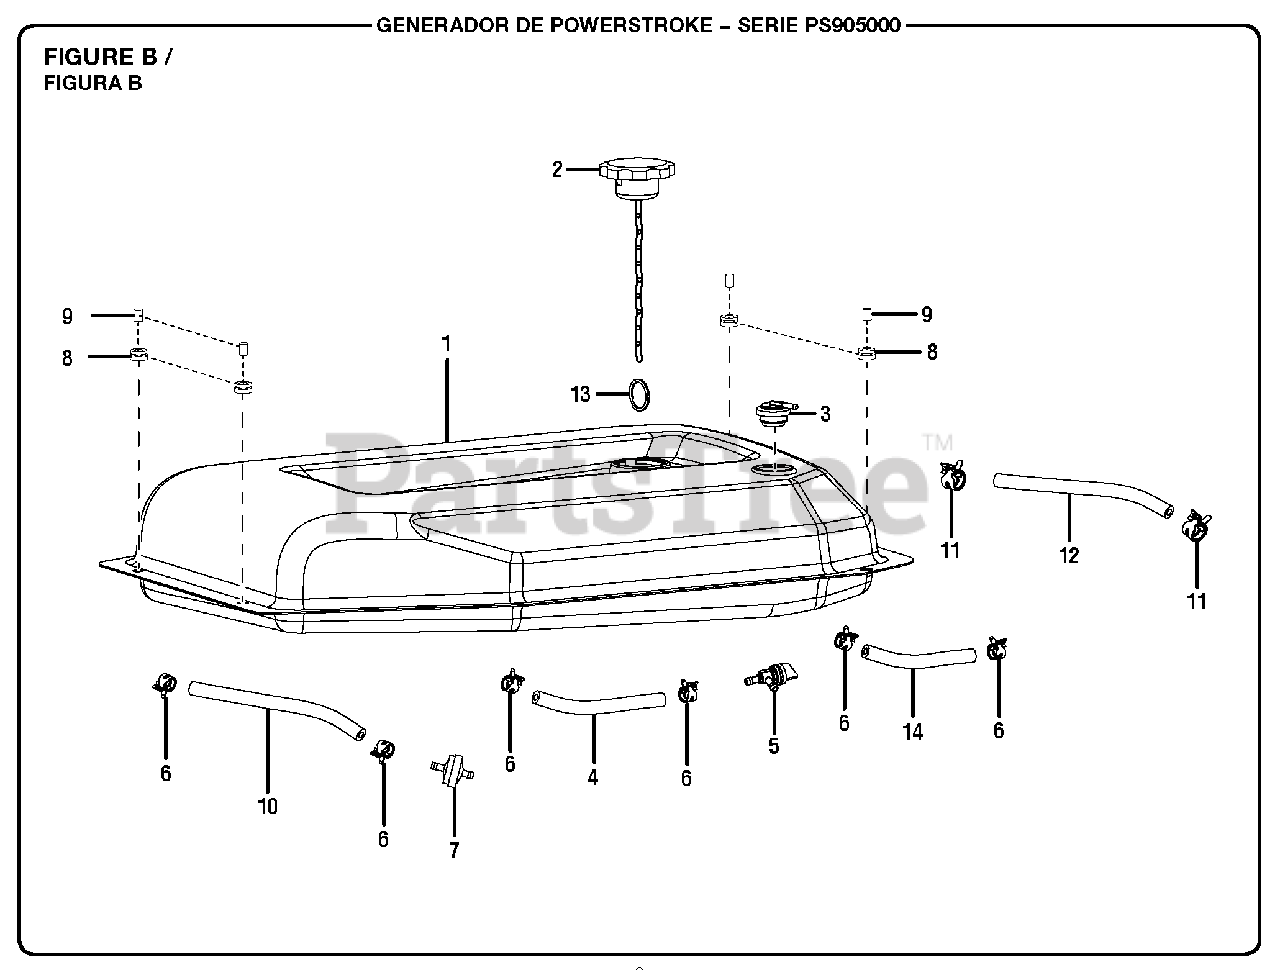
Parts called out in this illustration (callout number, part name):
1	Fuel Tank
3	Fuel Tank Vapor Vent
4	Fuel Line (6.4 mm x 72 mm)
5	Fuel Shut Off Valve
6	Fuel Line Clamp (1/2 in.)
7	Fuel Filter
8	Bushing (Fuel Tank Isolator)
9	Spacer (Fuel Tank Isolator)
10	Fuel Line (6.4 mm x 72 mm)
11	Fuel Line Clamp (7/16 in.)
12	Vapor Hose
13	Ring Clip
14	Fuel Line (6.4 mm x 85 mm)
